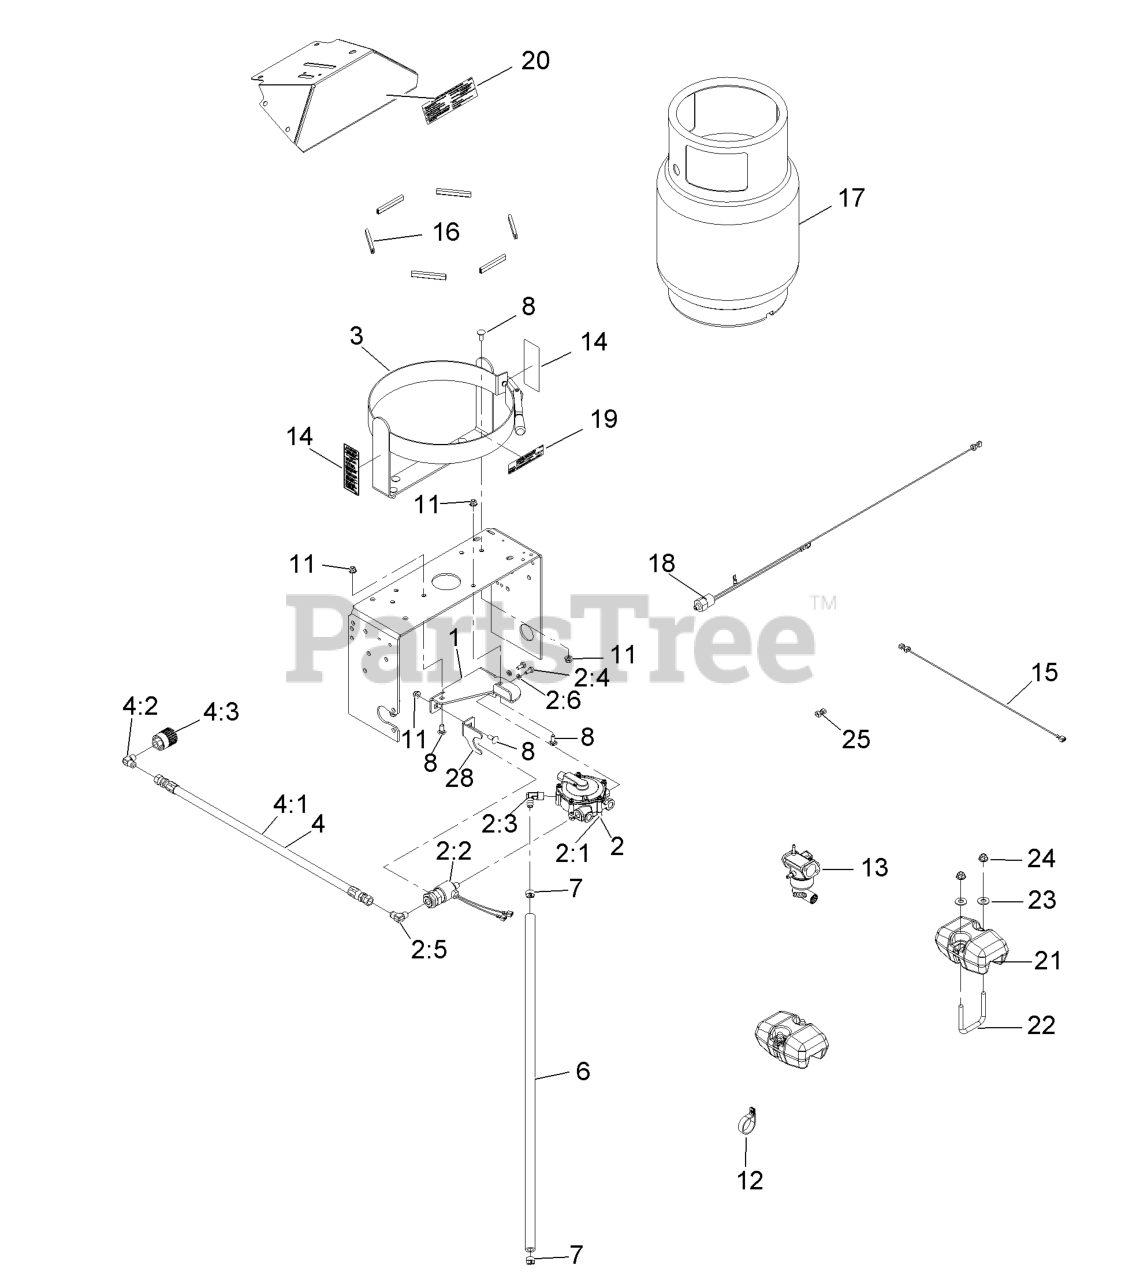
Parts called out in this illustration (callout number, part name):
1	REGULATOR MOUNT-THP
2	Asm, Reg And Shutoff
2:1	Regulator-Lp, T60
2:2	ASM, LPG FUEL SHUTOFF W/T
2:3	ELBOW-90 DEG
2:4	SCREW-HH
2:5	ELBOW 90DEG,1/4 NPT X3/8
2:6	WASHER-LOCK
4	Asm, Lpg Fuel Hose
4:2	ELBOW 90DEG,1/4 NPT X3/8
4:3	CONNECTOR-LPG TANK, LH TH
6	HOSE,LP 1/2 X 33
7	CLAMP-HOSE
8	BOLT-CARR
11	NUT-HF, NI
12	CLIP-LOOM
13	MIXER ASM, KA FS600V
14	DECAL-LPG WARNING
15	ASM, WIRE 20"
16	STRIP-SEAL
19	DECAL,LPG TANK SPEC VERTI
20	DECAL-TANK REPLACEMENT
21	WEIGHT-SUPPORT, CASTER
23	WASHER-FLAT
24	NUT-HF, NI
25	RECEPTICAL -FEM, .250, IN
28	SOLENOID SUPPORT
